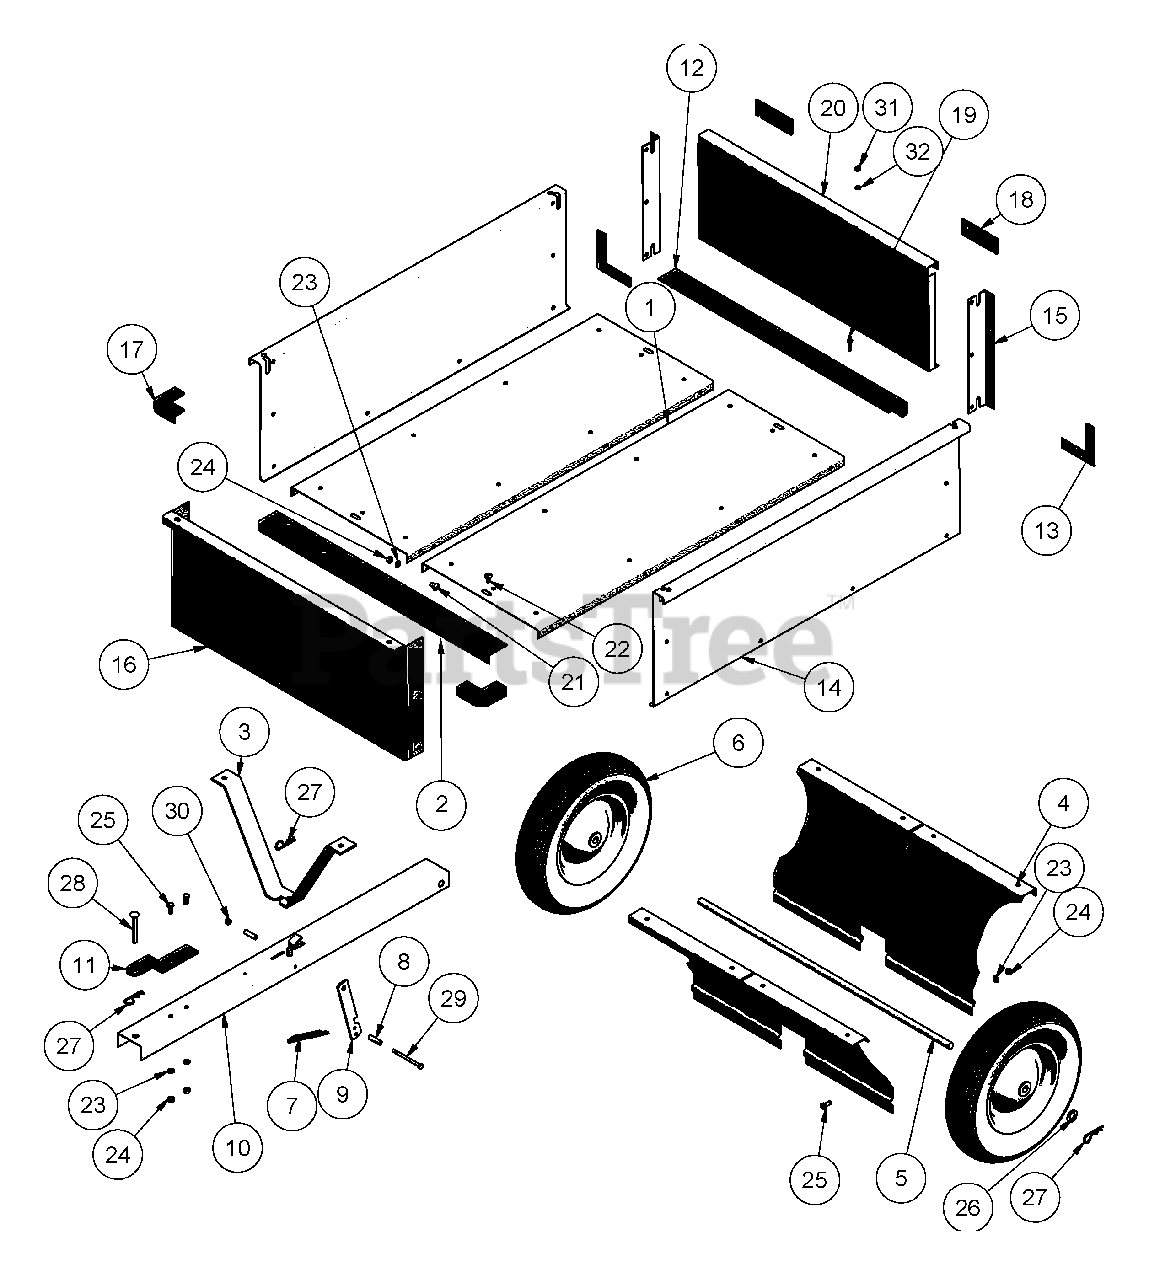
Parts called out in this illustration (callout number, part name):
1	BOTTOM PANEL
2	FRONT CROSS BRACE
3	TONGUE SUPPORT
4	WHEEL AXLE SUPPORT
5	WHEEL AXLE
6	WHEEL/TIRE ASSEMBLY
7	LATCH SPRING
8	LATCH SPACER
9	TONGUE LATCH
10	HITCH TONGUE
11	HITCH PIN BRACKET
12	REAR CROSS BRACE
13	REAR CORNER BRACKET
14	SIDE PANEL
15	REAR CORNER BRACE
16	FRONT PANEL
17	FRONT CORNER BRACE
18	TAILGATE LATCH
19	TAILGATE PIN
20	TAILGATE
21	M8 X 16 TRUSS HEAD BOLT
22	M8 X 20 TRUSS HEAD BOLT
23	8MM LOCK WASHER
24	8MM HEX NUT
25	M8 X 20 HEX BOLT
26	20MM FLAT WASHER
27	3MM HAIRPIN
28	HITCH PIN
29	M6 X 90 HEX BOLT
30	6MM NYLON NUT
31	6MM HEX NUT
32	6-8MM FLAT WASHER
